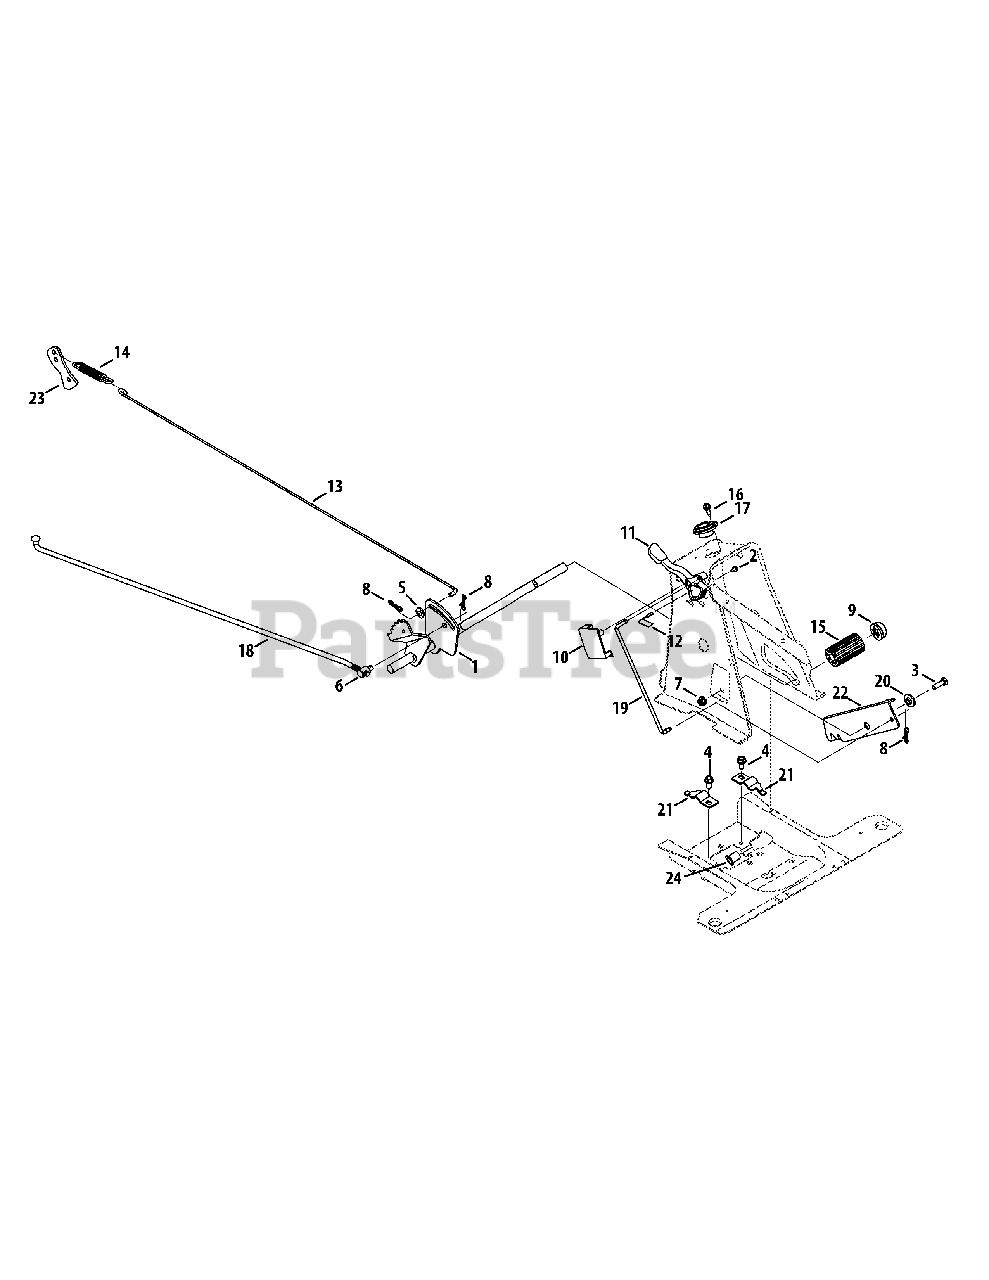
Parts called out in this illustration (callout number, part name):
1	Brake Pedal Assembly
2	Screw, #10-16:0.500
3	Hex Head Scerw, 5/16-18:1.00
4	Tap Screw, 5/16-18:.750
5	Flat Washer, .330 x .630 x .064
6	Ferrule 3/8-24 X .375 Dia.
7	Flange Lock Nut, 5/16-18
8	Bow-Tie Cotter Pin, 72
9	Push Cap, 5/8
10	Speed Control Cover
11	Speed Lever, 6-SPEED
12	Shift Spring
14	Extension Spring, .59 OD x 4.00 LG
15	Foot Pad, 2.5" LG.
16	Shoulder Screw, .368 X.113, 1/4-20
17	Steering Col. Bearing, .880 ID X 1.36
18	Variable Speed Control Rod
19	Speed Selector Control Rod
20	Shoulder Spacer
21	Pedal Strap Support Bracket, 5/8
22	Speed Latch Bracket
23	Brake lever Bracket
24	Flange Bearing, .626 x .938 x .875
